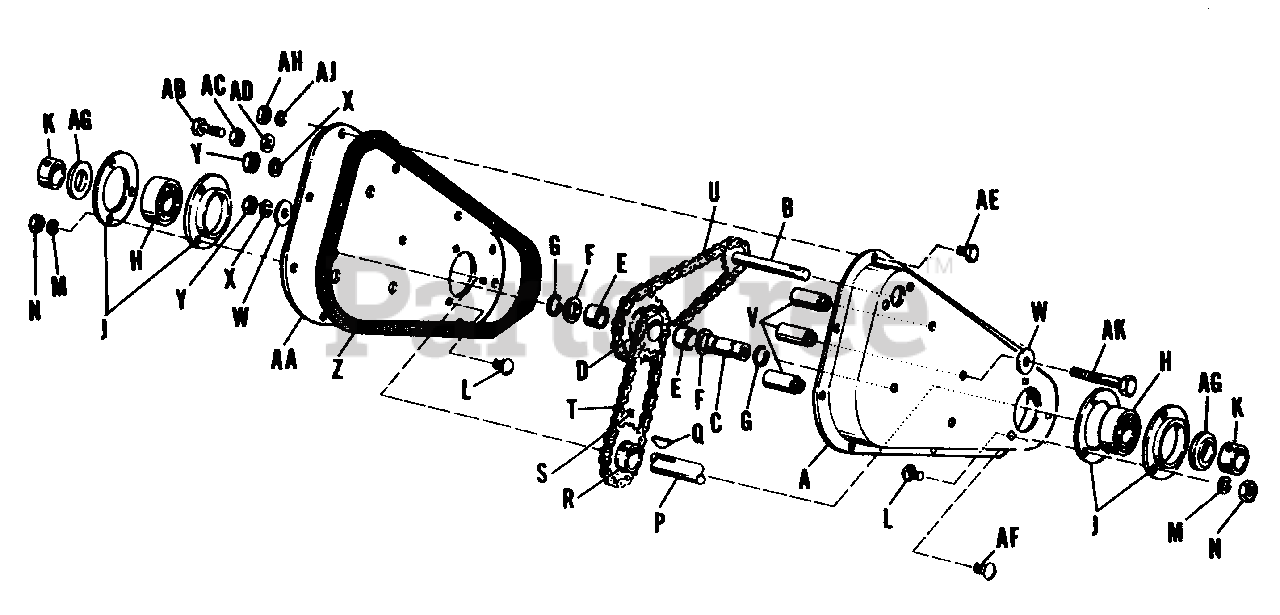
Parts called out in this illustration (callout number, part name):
A	Guard Assembly, Chain
B	Shaft Assembly Drive
C	Spacer, Intermediate
D	Sprocket Assembly
E	Bearing, Roller
G	Ring, Retaining
J	Flange, Bearing
K	Collar, Bearing
L	Bolt Carriage, 3/8"-16 NC x 3/4" lg.
M	Washer Lock 3/8"
N	Nut, Hex, Full 3/8"-16 NC
P	Shaft Tine
Q	Key, Hi-Pro., 1/4" x 7/8"
S	Screw, Set Cup Point, Socket Hd. 5/16"-18 NC x 5/16" lg.
T	Chain, Rotor
U	Chain, Drive
V	Spacer, Guard
X	Washer, Lock 7/16"
Y	Nut, Hex, Full 7/16"-14 NC
AA	Plate Assembly
AB	Capscrew, Hex. 3/8"-24 NF x 2-1/2" lg.
AC	Nut, Hex, Jam, 3/8"-24 NF
AD	Washer Plain 3/8"
AE	Capscrew, Hex, 5/16"-18 NC x 5/8" lg.
AF	Carriage, Bolt 5/16"-18 NC x 3/4" lg.
AH	Nut, Hex, Full 5/16"-18 NC
AJ	Washer, Lock 5/16"
AK	Capscrew Hex, 7/16"-14 NC x 3-3/4" lg.
